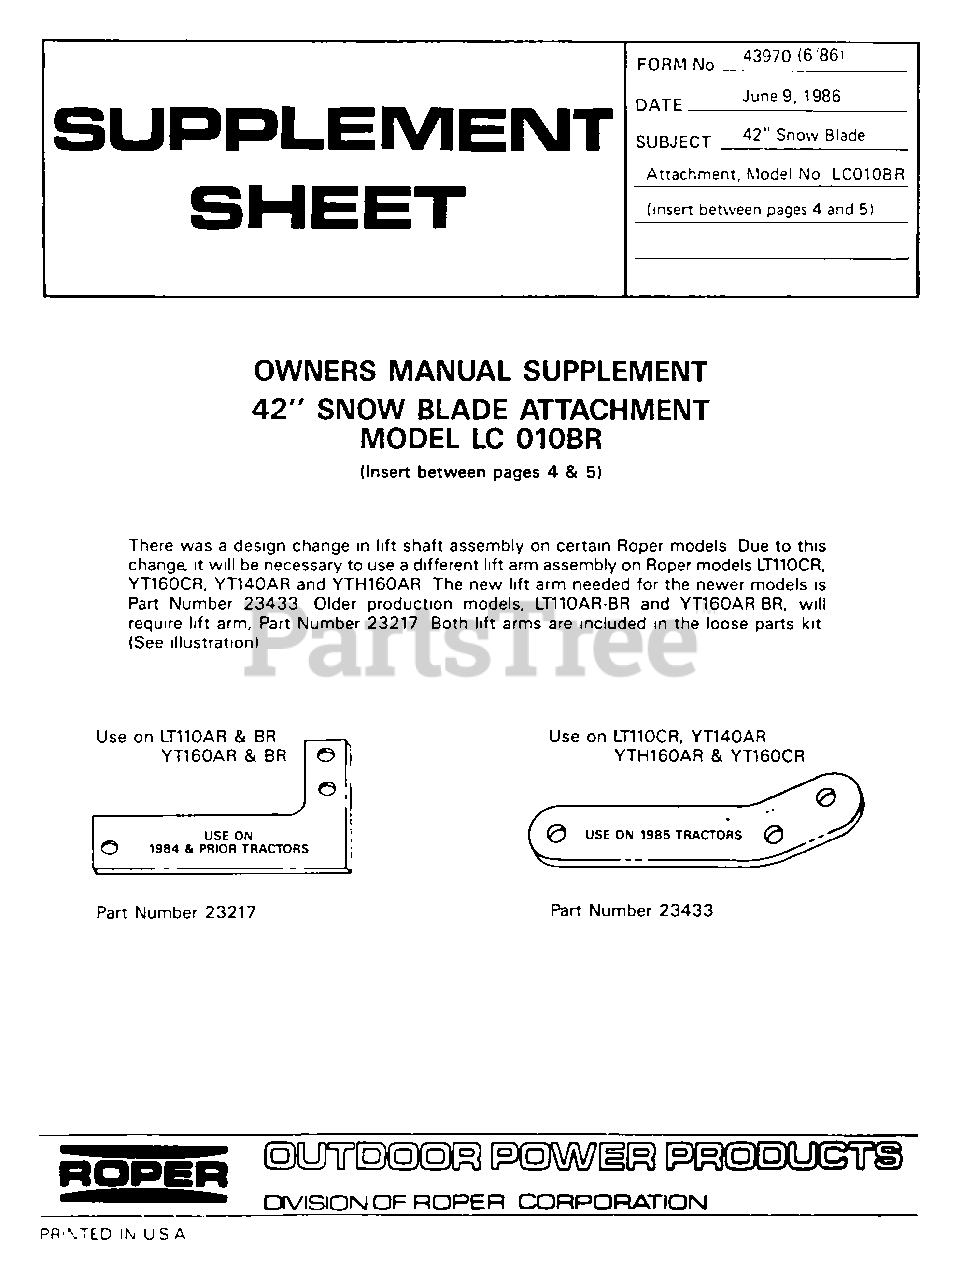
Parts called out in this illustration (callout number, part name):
10	PIVOT PLATE ASSY
11	CHANNEL ASSY
12	LIFT HANDLE ASSY
13	HANDLE GRIP
15	No Desciption for Part
19	BAR ANGLE LO
